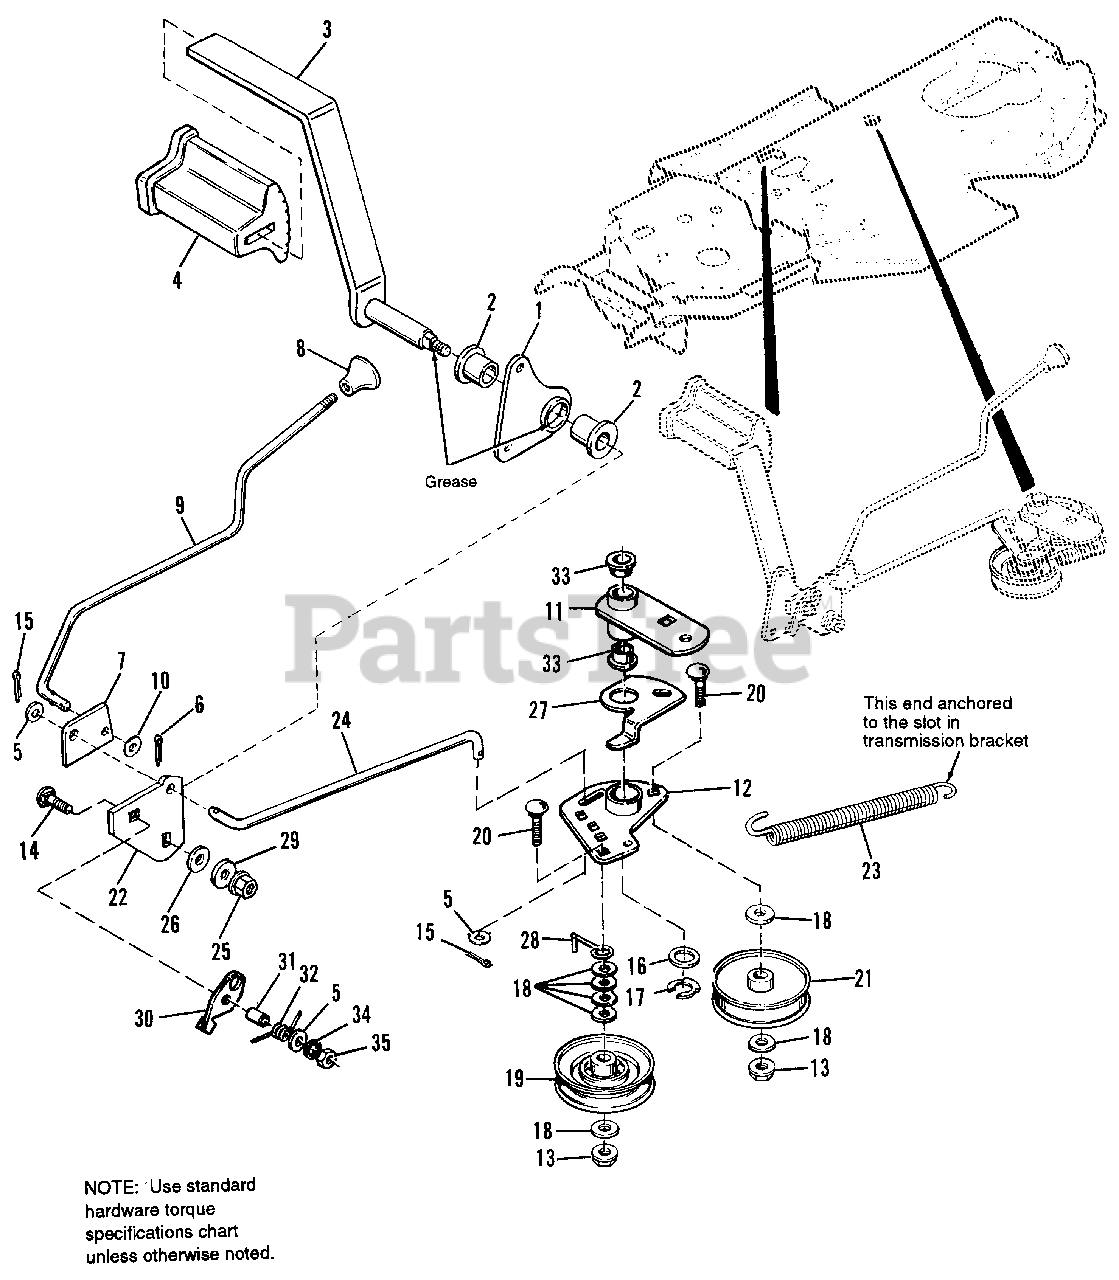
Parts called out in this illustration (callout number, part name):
2	BUSHING, Plastic
3	BRAKE PEDAL ASSY.
4	PAD, Foot Pedal
5	WASHER, Plain, 5/16
6	COTTER PIN
7	CAM, Parking Brake
8	KNOB, Plastic
9	ROD, Parking Brake
10	WASHER, Plain, 9/32
11	PIVOT ASSY., Shift
12	IDLER ARM ASSY.
13	NUT, Flange Whizlock, 3/8-16
14	CARRIAGE BOLT, 5/16-18 x 1-1/4
15	COTTER PIN
16	WASHER, 5/8
17	KLIPRING, 5/8
18	WASHER, Plain, 13/32
20	CAPSCREW, 3/8-16 x 1-3/4
21	PULLEY, Idler, Flat
22	ARM, Foot Pedal
23	SPRING, Drive
24	ROD, Clutch, 5/16 Dia.
25	NUT, Hex, Esna, 3/8-16
26	WASHER
27	LEVER, Lockout
29	WASHER, 13/32 x 1-1/2 x 1/16
30	ACTUATOR, Switch
32	SPRING, Tension
33	BUSHING, Plastic
34	LOCKWASHER, 5/16
35	NUT, Hex, 5/16-18
